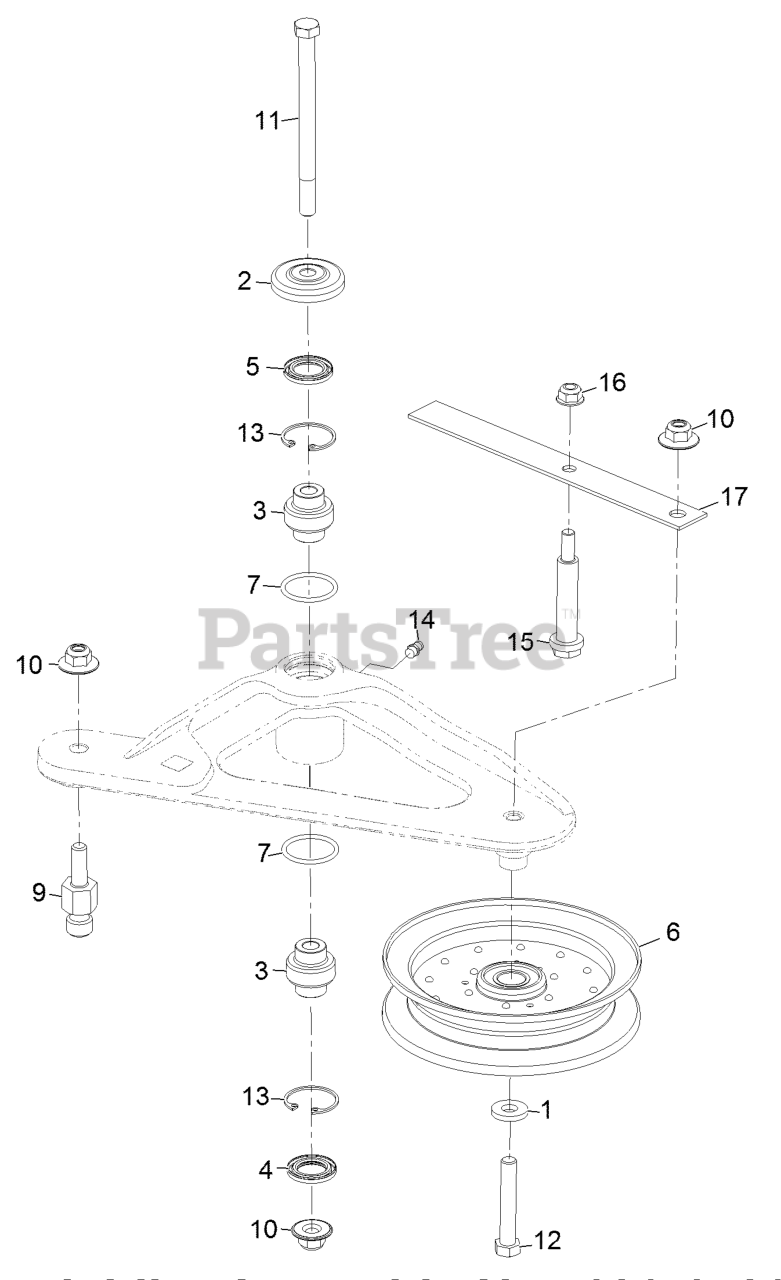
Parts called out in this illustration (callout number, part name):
2	GUARD-TOP
3	BEARING-SPHERICAL
4	SEAL-LIP, DOUBLE
5	SEAL-LIP, SINGLE
9	PIN-SPRING, ANCHOR
10	Nut-Nyloc 3/8-16 Flg
11	SCREW-SHOULDER, HH
12	SCREW-HH
13	RING-SNAP
14	FITTING-GREASE
15	BOLT-SHOULDER
16	NUT-HF, NI
17	SPRING-BELT
